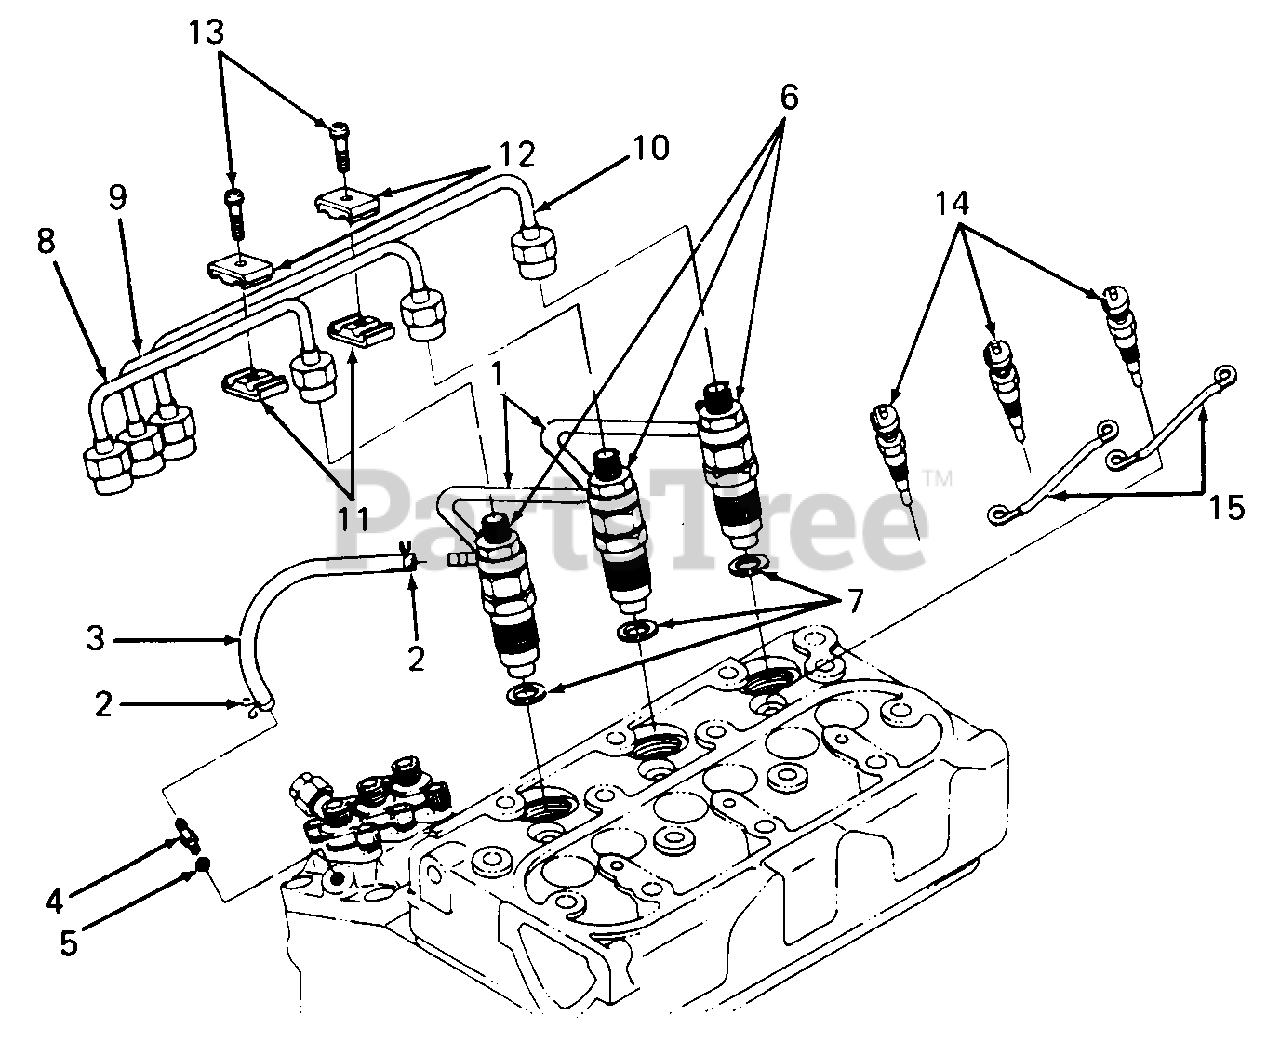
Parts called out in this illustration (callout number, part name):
1	Pipe, Overflow
3	Pipe, Overflow
6	Nozzle, Injection
7	Gasket
8	Pipe, Injection - 1
9	Pipe, Injection - 2
10	Pipe, Injection - 3
13	Screw w/Washer
14	Plug, Glow
15	Wire, Glow Plug
